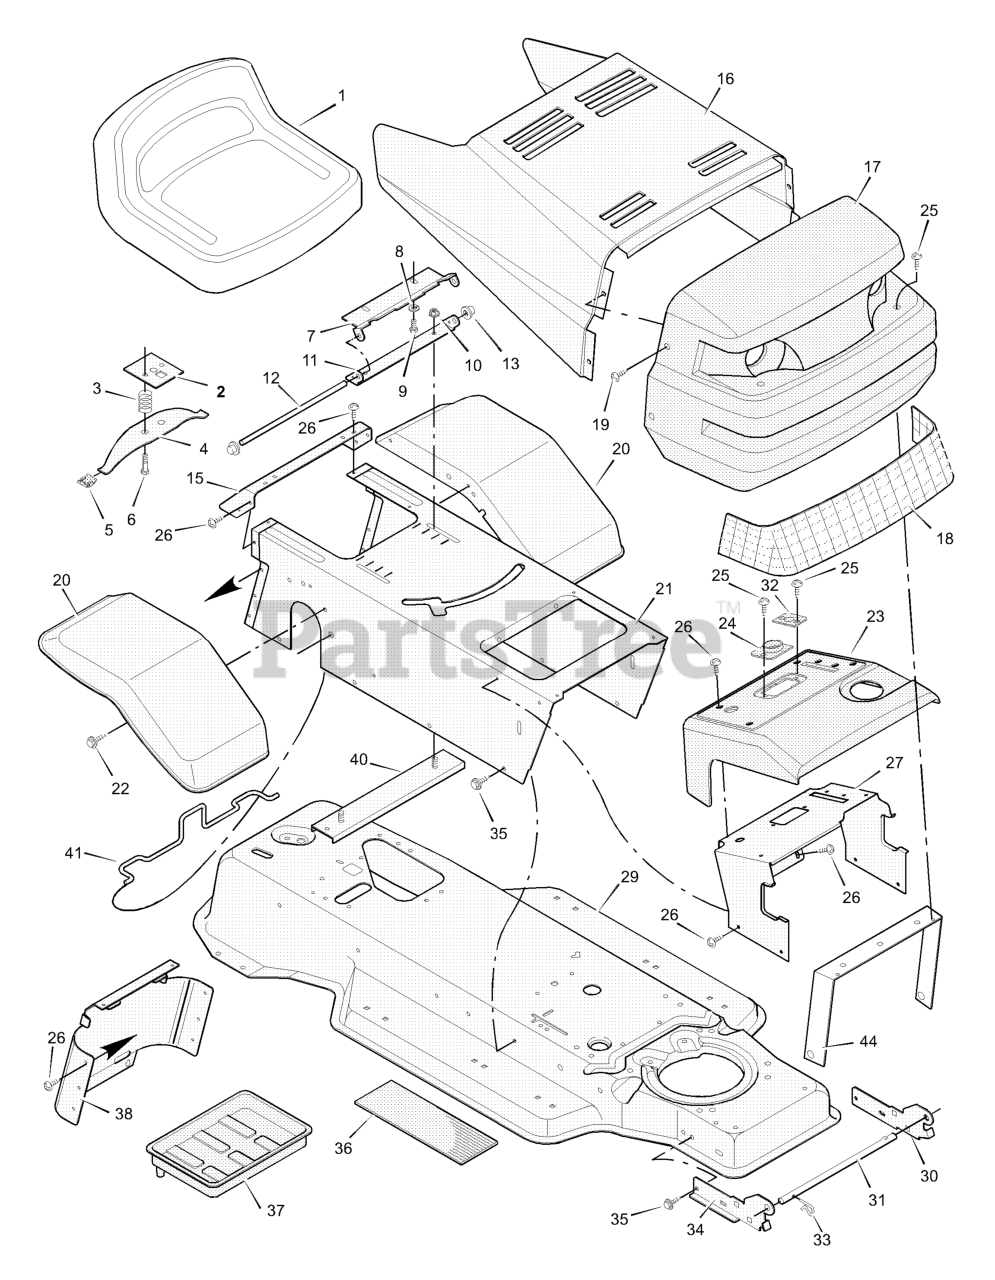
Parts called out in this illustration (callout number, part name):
2	Plate Assembly, Switch
3	Spring, Compression
4	Spring, Seat
5	Glide, Spring
6	Bolt, Shoulder
7	Support, Seat
8	Lockwasher
9	Bolt, Hex
10	Locknut, Flange
11	Bracket, Pivot
12	Rod, Pivot
13	Cap, Push On
15	Fender, Apron
17	Grille Assembly
21	Console Assembly
23	Dash Panel
24	Bearing, Steering
26	Screw
27	Support, Dash
29	Frame Assembly
30	Bracket, Left Grille
31	Rod, Pivot
32	Bearing
33	Pin, Hair
34	Bracket, Right Grille
37	Tray, Battery
38	Cap, Console
39	Bolt
40	Channel Assembly
41	Clamp, Battery
44	Brace, Grille
